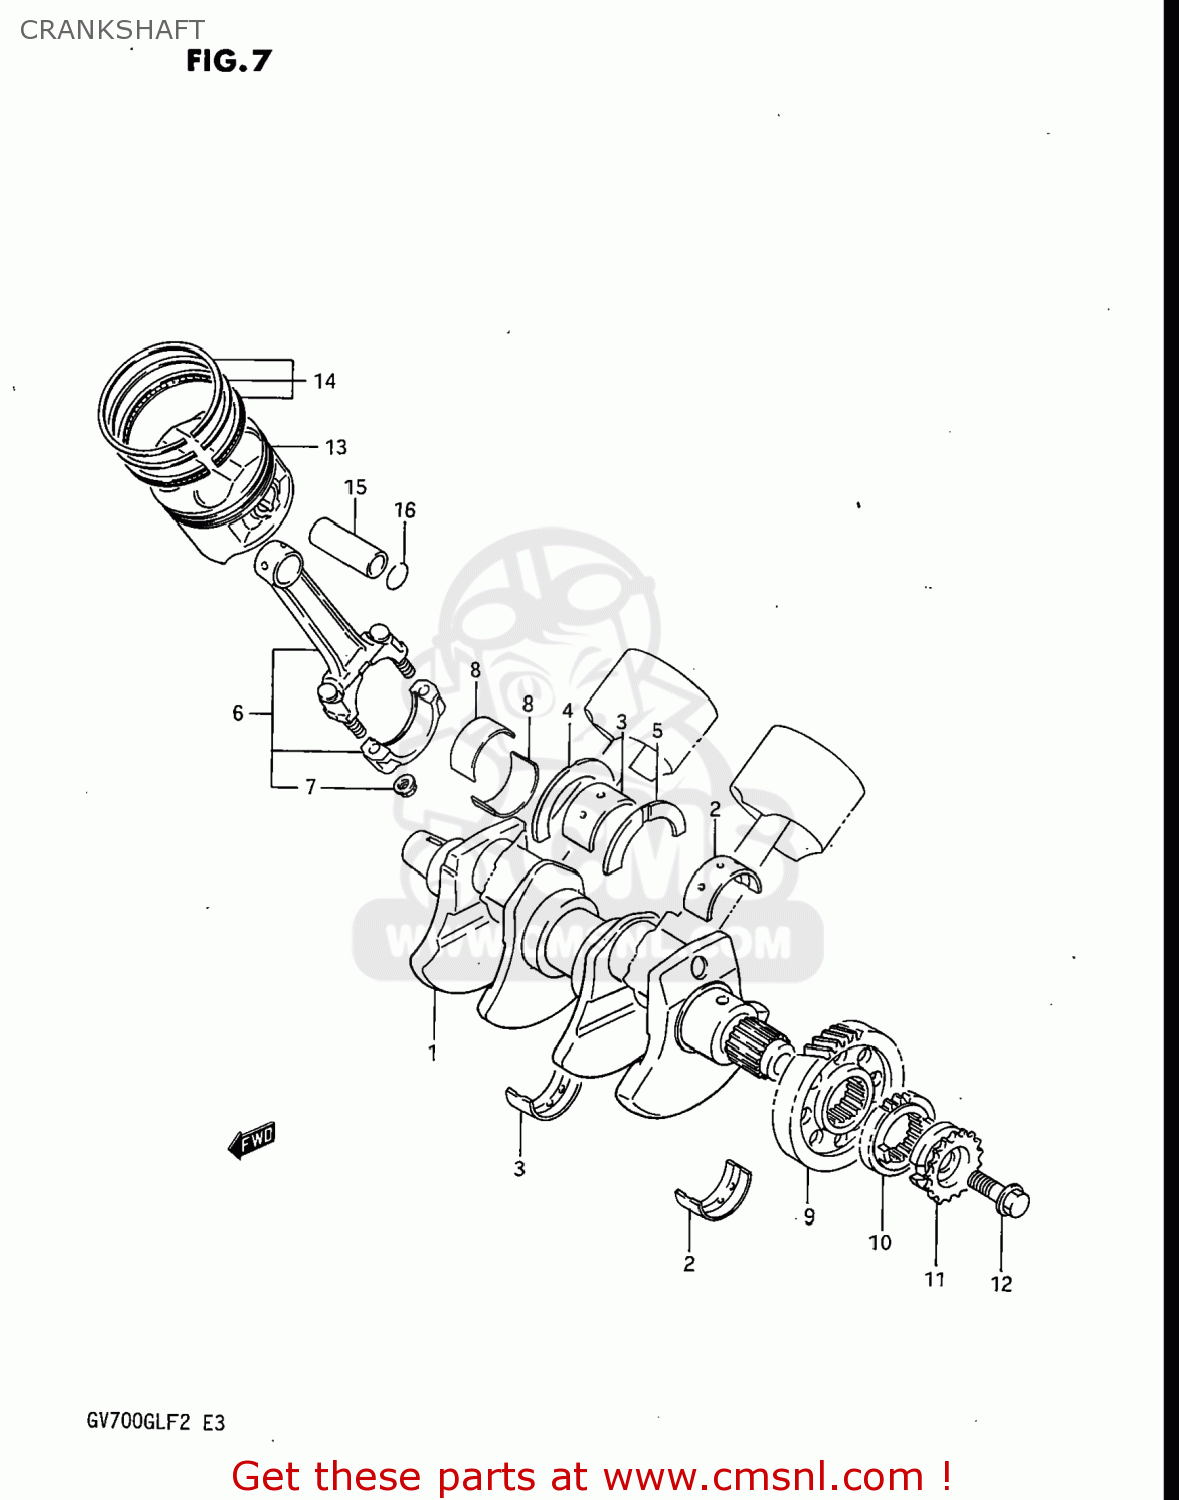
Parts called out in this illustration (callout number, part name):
1	CRANKSHAFT
2	METAL CRANKSHAFT
3	METAL CRANKSHAFT
4	PLATE,CRANK THRUST
5	PLATE,CRANK THRUST
6	CONNECTING ROD ASSEMBLY
7	NUT
8	BEARING,CRANK PIN
9	GEAR,PRIMARY DRIVE
10	SPROCKET,CHAIN DRIVE I
11	SPROCKET,WATER PUMP DRIVE
12	BOLT 12X30
13	PISTON (STD)
14	RING SET,PISTON
15	PIN,PISTON
16	CIRCLIP
